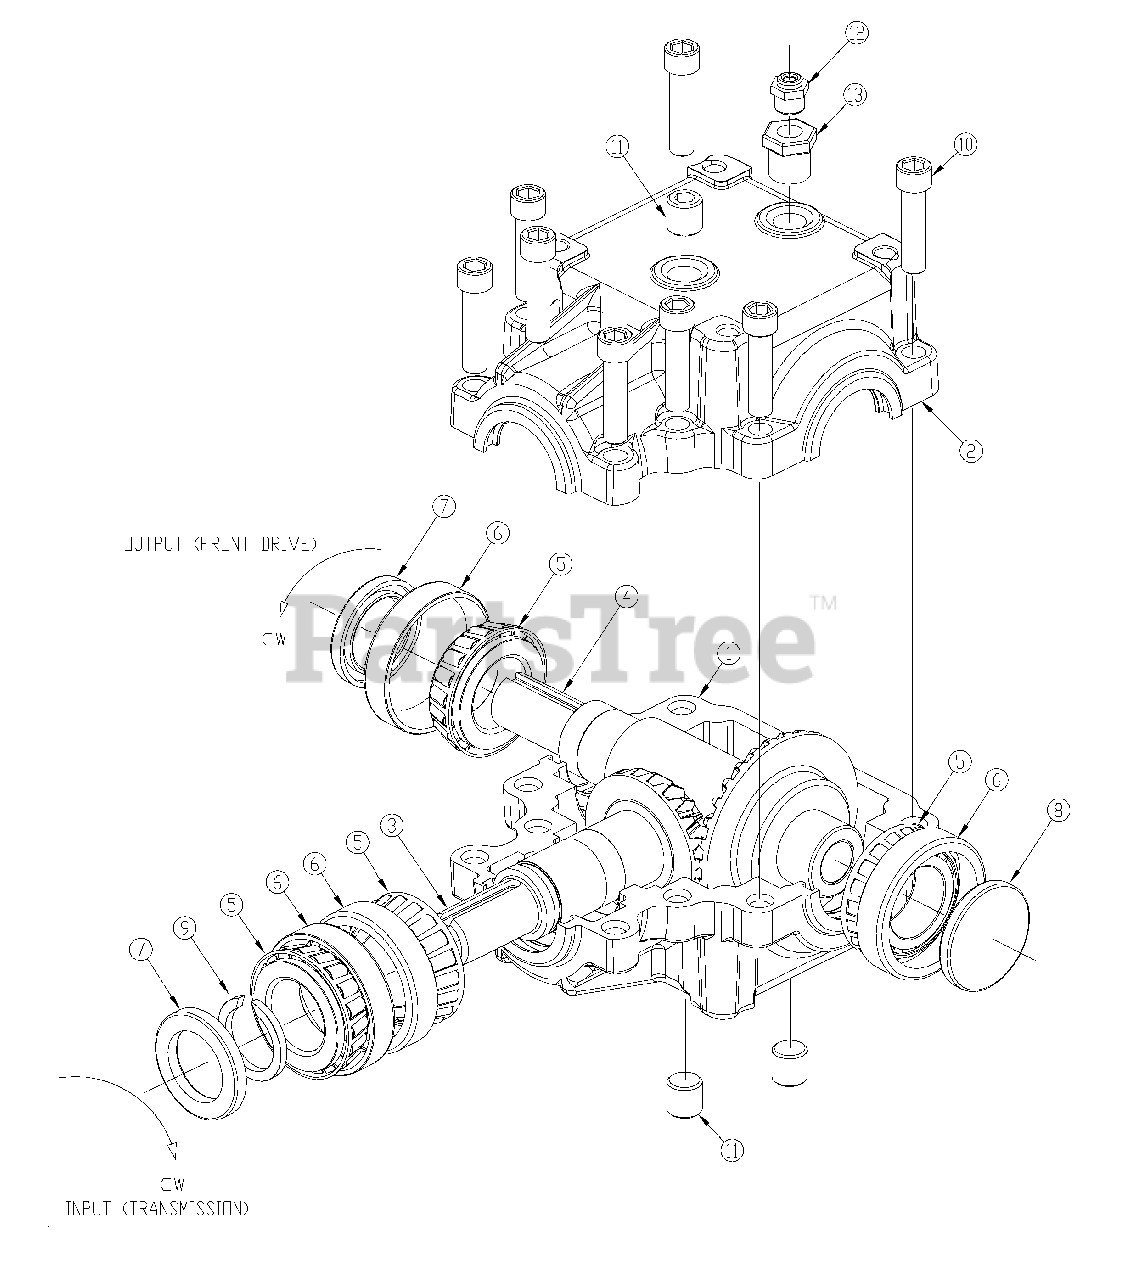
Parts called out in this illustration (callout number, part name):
1	GBOX MODEL R100 1.5TO1 RATIO
1	SUPERIOR HSG,R100 MACH TAP STD
2	SUPERIOR HSG,R100 MCH THRU STD
3	SUPERIOR STUB SHAFT/GEAR ASSY
4	SUPERIOR CROSS SHAFT/GEAR ASSY
5	SUPERIOR BRG CONE1.00VN-L44643
6	RPBY 822-080C
7	SUPERIOR SEAL,1-1.5-.187(R)TC
8	SUPERIOR CAP,CP-1.5-.187D#7647
9	SUPERIOR RTN RING EXT1.000SHFT
10	SUPERIOR BOLT 5/16-18X1.25SHCS
11	SUPERIOR PLUG 1/4-18NPT SCHD
12	SUPERIOR PLUG VNT5PSIV/N005677
13	SUPERIOR BUSHING 1/4NPTX1/8NPT
